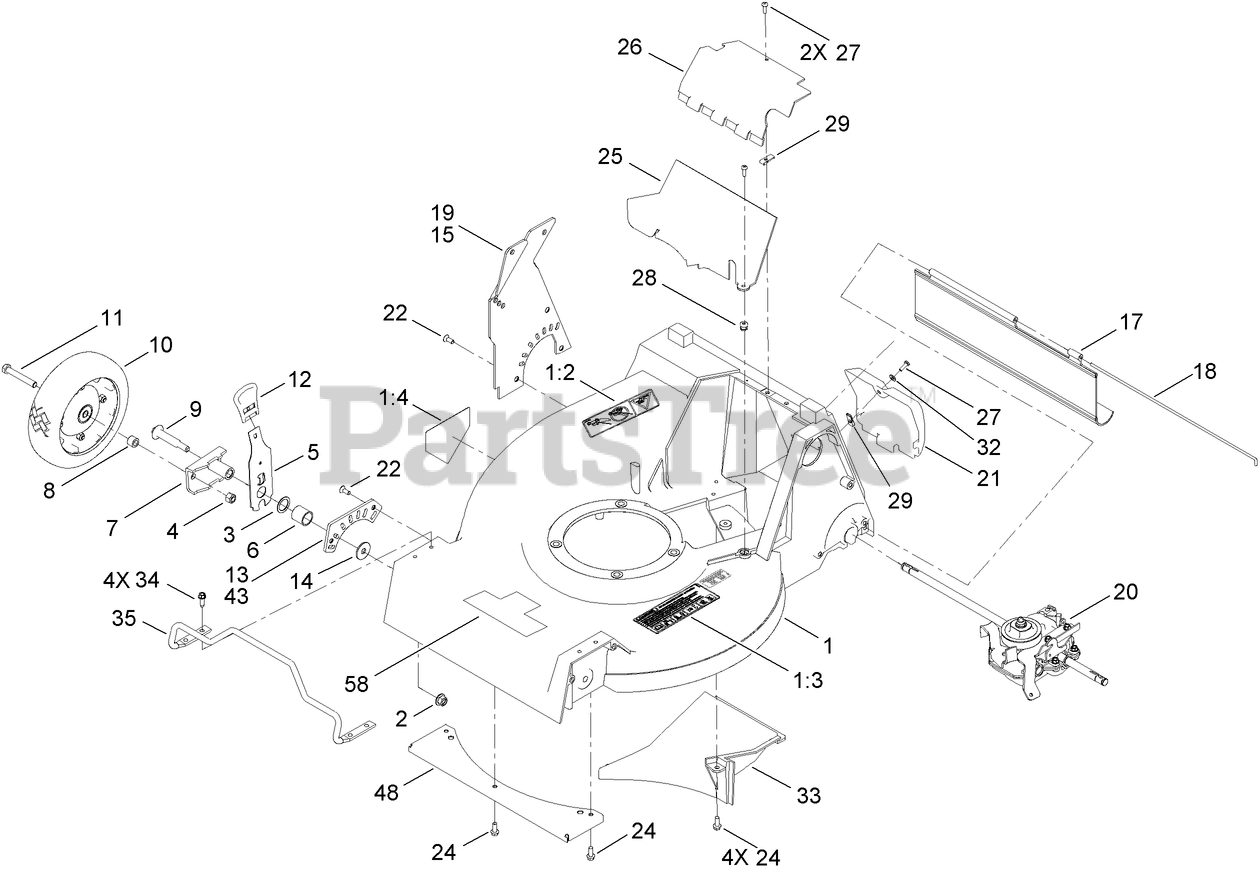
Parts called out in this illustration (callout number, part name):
1	DECK ASM
1:2	DECAL-DANGER
1:3	DECAL-DANGER
1:4	DECAL-DANGER
2	NUT-LOCK
3	WASHER
4	NUT-LOCK, CONE
5	FRONT SPRING ARM ASM
6	SPACER-BEARING
7	ARM-PIVOT, FRONT
8	SPACER-WHEEL
9	SCREW-SHOULDER
10	WHEEL AND TIRE ASM
11	SCREW-HH
12	KNOB-HOC
14	WASHER
15	PLATE-REAR HOC, RH
17	SHEILD-TRAILING
18	ROD-SHIELD
20	GEAR CASE ASM
21	DOOR-ACCESS, REAR
22	SCREW-HH
24	SCREW-HWH
25	COVER-BELT, LOWER
26	COVER-BELT, UPPER
28	NUT-CLIP
29	NUT-TYPE J
32	WASHER-FLAT
33	BAFFLE-CHUTE, FLOOR
34	SCREW-HWHTF
35	GUARD-ENGINE
43	PLATE-FRONT HOC, RH
48	SHIELD-FRONT, HI-VAC
58	DECAL
